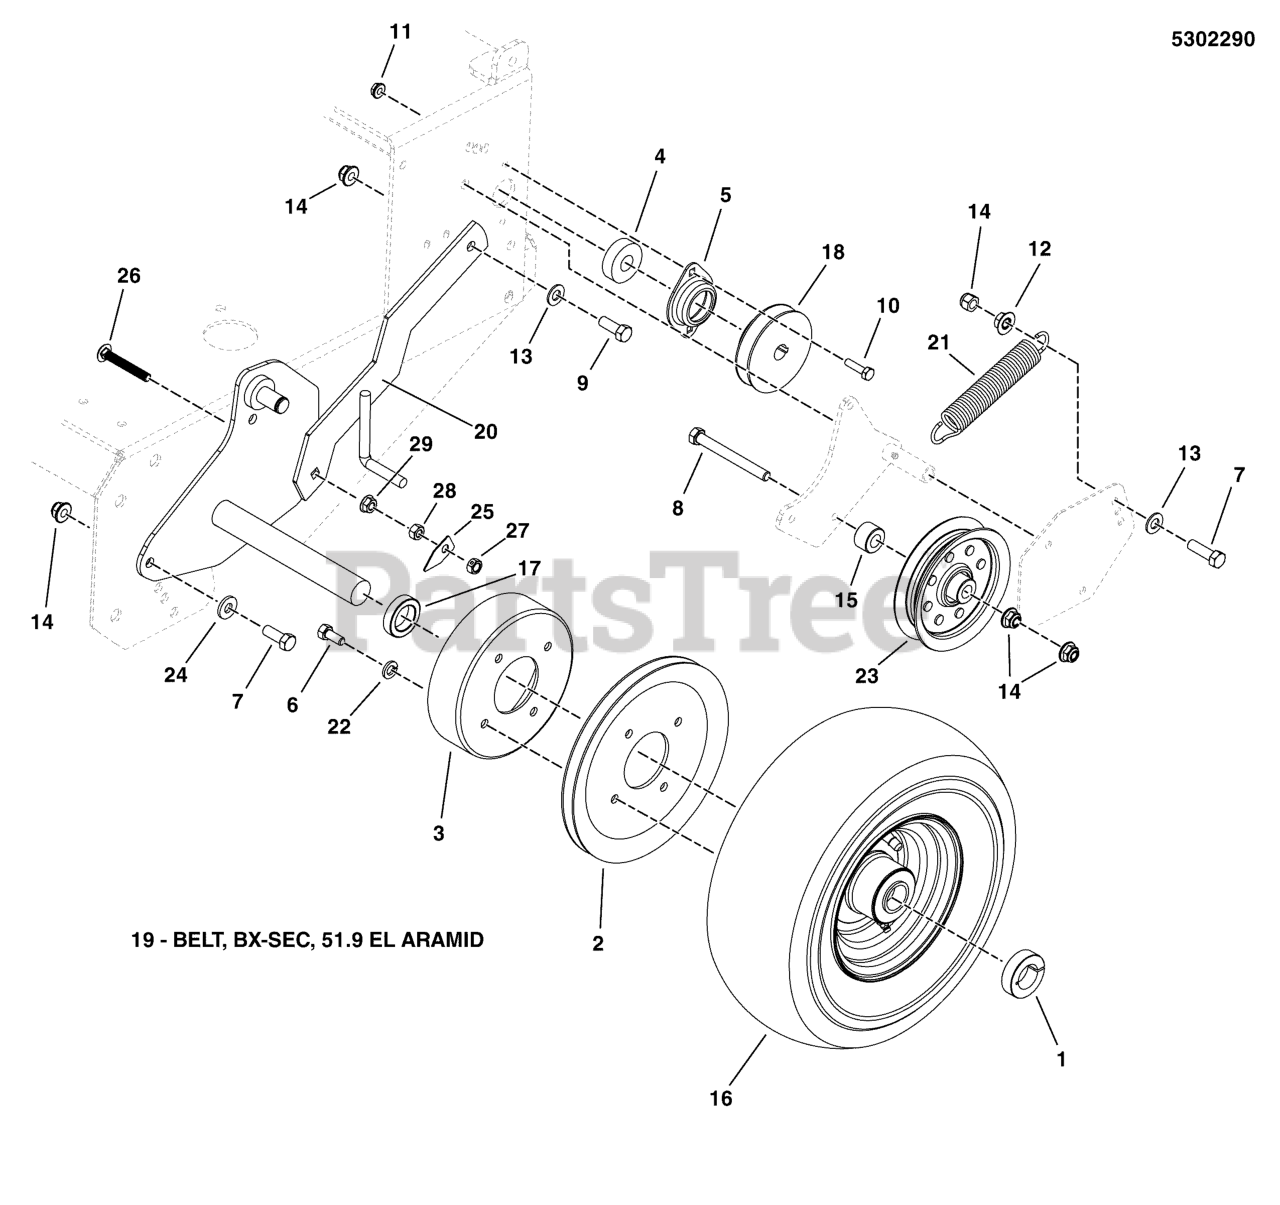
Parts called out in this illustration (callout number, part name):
1	COLLAR, 1 SPLIT
2	PULLEY, 8" OD, B-SEC, BGF32
3	DRUM, 6 BRAKE
4	BEARING, 5/8
5	FLANGE, 5/8 BEARING MOUNT
6	BOLT, 5/16-18 X 3/4 GD5
7	BOLT, 3/8-16 X 1-1/4" GD5 CZ
8	BOLT, 3/8-16 X 2-3/4" GD5 CZ
9	BOLT, 3/8-16 X 1" GD5 CZ
10	BOLT, 1/4-20 X 1" GD5 CZ
11	NUT, 1/4-20 HEX SERR. FLANGE
12	NUT, 3/8-16 HEX SERRATED FLANGE
13	WASHER, 3/8 SAE
14	NUT, 3/8-16 HEX NYLOCK FLANGE
15	SPACER, .39 X 1.00 X .50, CZ
16	TIRE/WHEEL ASM, 13 X 5, BELT DRIVE
17	SPACER, 1.02 X 1.56 X .38
18	PULLEY, 3.25 OD X .625 ID, SINGLE B-SEC.
20	WELD, REAR AXLE - RED
21	SPRING, EXT, 1.00 X 4.55 X .115 WIRE,BLK
22	WASHER, 5/16 LOCK CZ
23	PULLEY-IDLER, 4.06OD, .375ID, .75W STL
24	BELLEVILLES WASHER, .38 X .875 X .109
25	GROOVE CLEANER, SW5
26	BOLT-RD HD SH SQ NK 5/16-18X2.250 G5 FUL
27	HCLN, 5/16-18 GR5 YZ
28	NUT, 5/16-18 HEX
29	NUT, 5/16-18 HEX SERRATED FLANGE (SMALL)
